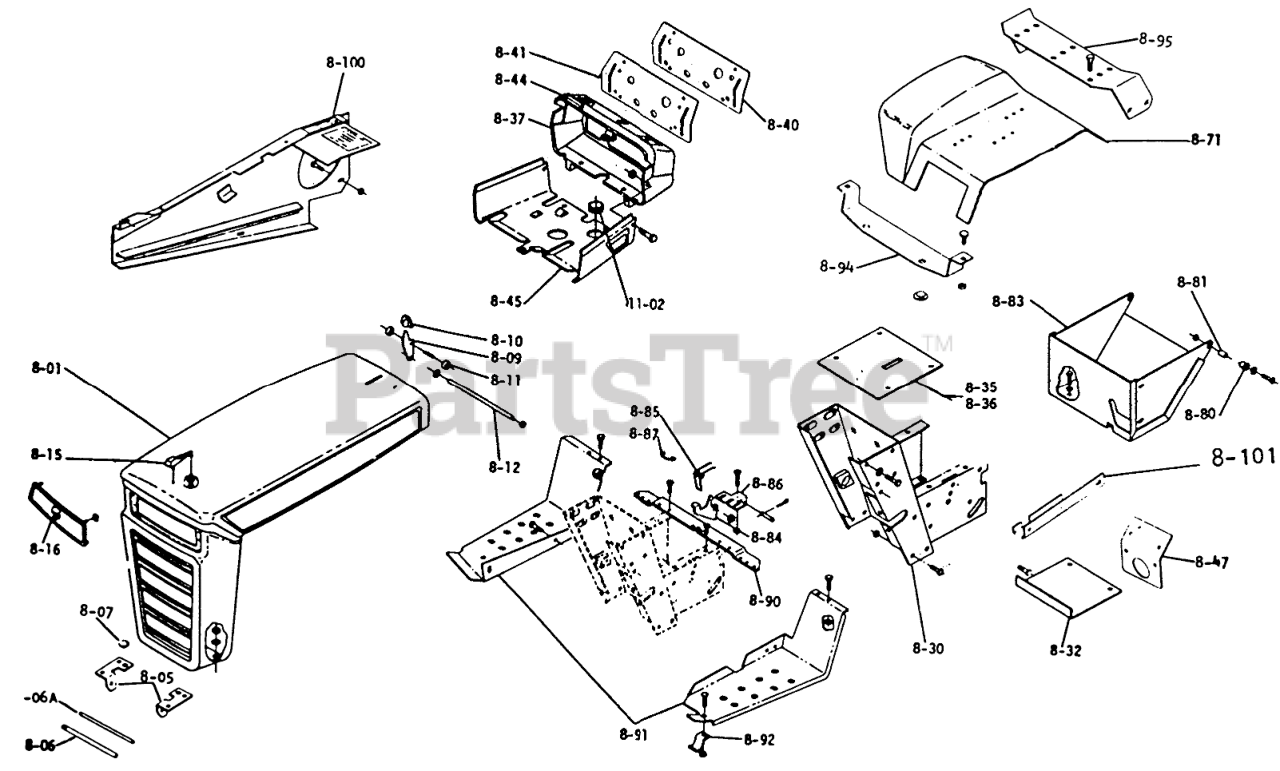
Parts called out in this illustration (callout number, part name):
8-05	Bolt Hex 5/16-18 x 3/4
8-05	Nut-Nylok
8-06	GRILL PIVOT ROD
8-06A	ROD-HOOD STOP
8-06A	Cotter Pin
8-07	GROMMET
8-09	LEVER HOOD LATCH
8-09	SPIROL PIN
8-10	KNOB
8-12	Nut-Hi Crown
8-15	Hood Ornament
8-15	Washer, Rubber
8-16	ESCUTCHEON PLATE
8-16	SPEED NUT
8-30	Bolt 3/8-16 x 1
8-32	Cover-Dust
8-32	Bolt 5/16-18 x
8-32	Nut-Nylok
8-35	Plate-Cover-Instructions
8-37	Bolt 1/4-20 x 5/8 Whizlock
8-37	Nut-Nylok
8-45	Screw 5/16-18 x 3/4 S.T.
8-47	Bolt, 1/4-20 Whizlock
8-71	Fender
8-80	BUSHING-FLANGED
8-81	Bolt 3/8-16 x 7/8
8-81	Washer
8-81	Spacer
8-81	Bolt-Car. 5/16-18 x 1
8-83	Bolt 3/8-16 x 3/4
8-83	Lockwasher
8-85	Spring
8-85	NYLINER BUSHING
8-85	Hairpin
8-86	Bolt-Hex 1/4-20
8-86	Nut-Nylok
8-90	Bolt 5/16-18 x 1
8-91	Bolt 5/16-18 x
8-91	Nut 5/16-18
8-91	Bolt, 5/16-18 x 1/2
8-92	BRACKET
8-92	Bolt Hex 5/16-18 x 3/4
8-92	Nut 5/16-18
8-94	Bolt Hex 5/16-18 x 3/4
8-94	Nut-Nylok
8-94	GROMMET
8-100	Bolt Hex 7/16-4 x 3/4
8-100	Bolt 3/8-16 x 3/4
8-100	Lockwasher 3/8
8-100	Washer 7/16
